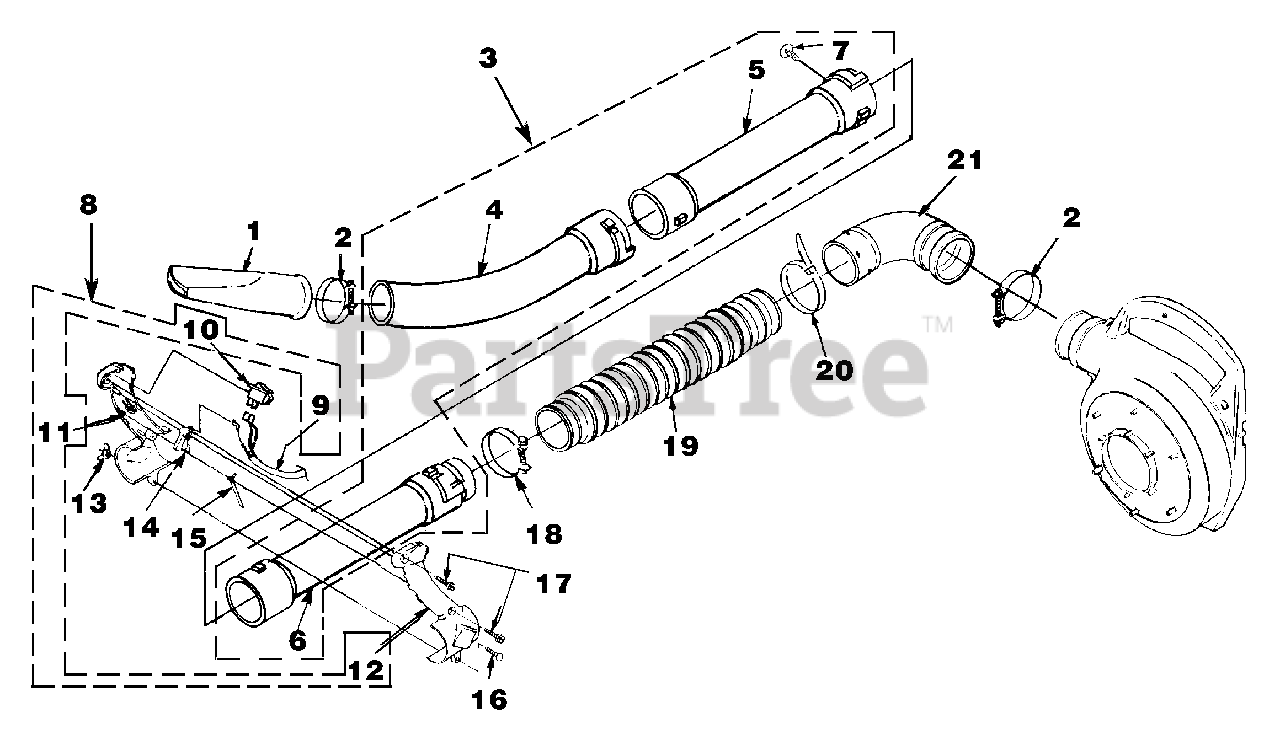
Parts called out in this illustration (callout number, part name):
1	NOZZLE-Sweeper
2	CLAMP
3	BLOWER TUBE KIT
4	TUBE-Elbow
5	TUBE-Straight
6	TUBE-Upper
7	CLIP-Push
8	HANDLE & SWITCH KIT
9	ELECTRICAL LEAD w/Terminal
10	SWITCH
11	HANDLE-Control (Right)
12	HANDLE-Control (Left)
13	NUT - Wing (10-24)
14	TRIGGER
15	LATCH-Trigger
16	BOLT-Rib Neck, Rnd. Hd. (10-24 X 7/8")
17	SCREW-Thread Form. (10-14 X 3/4")
18	CLAMP (#87)
19	BELLOWS-Plastic
20	CABLE-Tie
21	ELBOW-Curved
